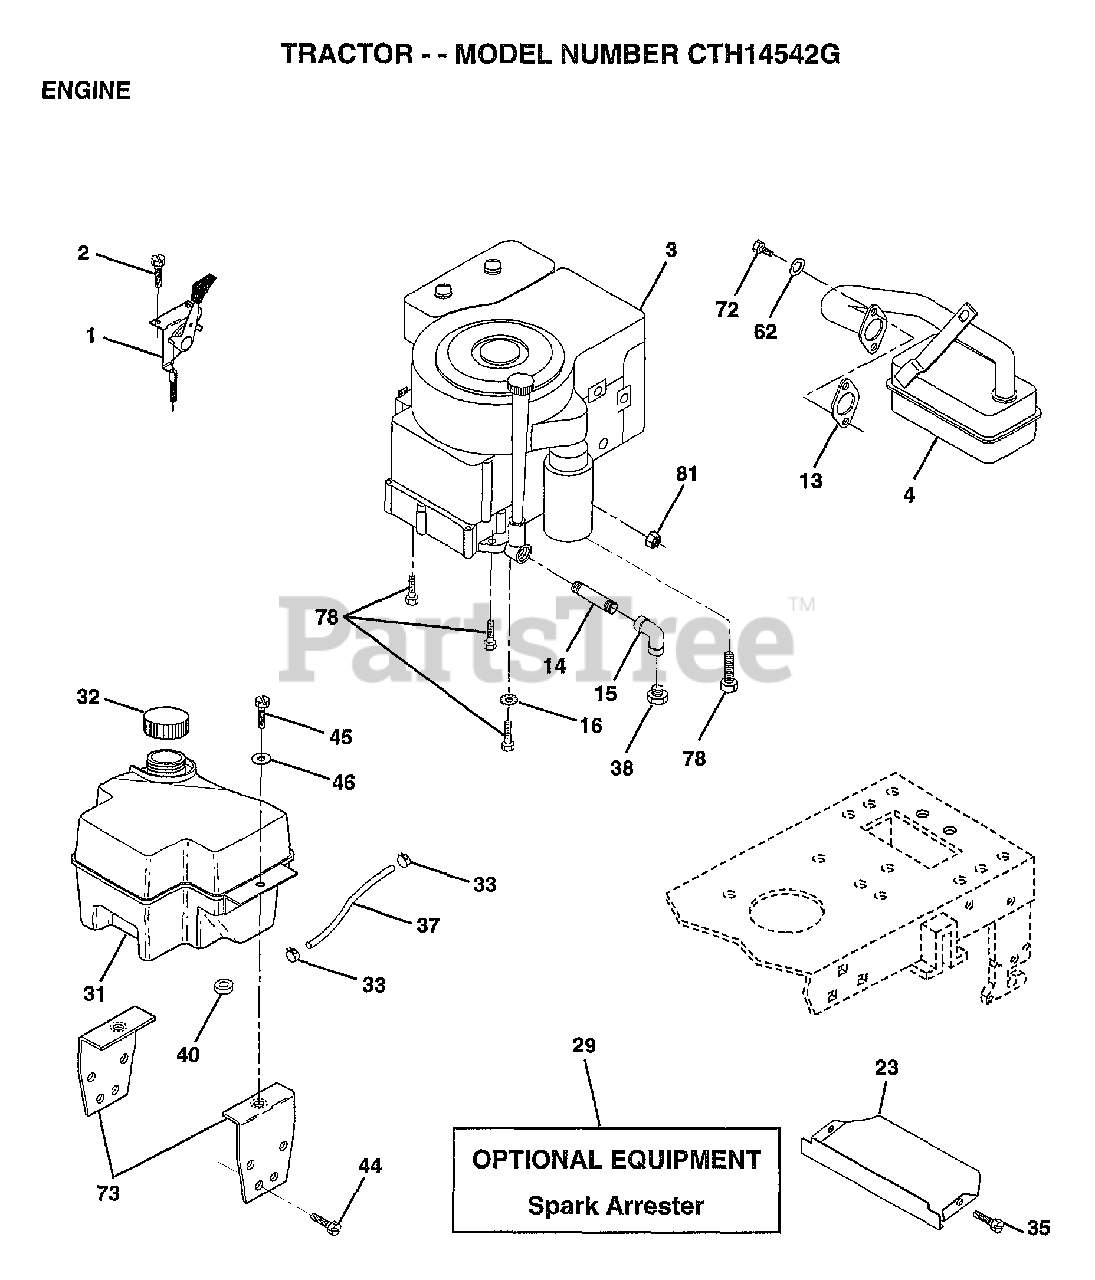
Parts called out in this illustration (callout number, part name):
1	CONTROL.THTL.19.6
2	SCREW LT
4	MUFFLER
13	GASKET ENG 1 313 LD TIN PLATED
14	PIPE NIPPLE
15	ELBOW
16	LOCKWASHER
23	SHIELD.BRN/DBR.GD
31	TANK.FUEL.FRONT.
32	CAP ASM FUEL
33	HOSE CLAMP
35	SCREW
37	LINE FUEL
44	SCREW
45	SCREW HEX CRT
46	WASHER
62	LOCKWASHER
72	SCREW
73	BRACKET.SUPT.TANK
78	SCREW
81	NUT
